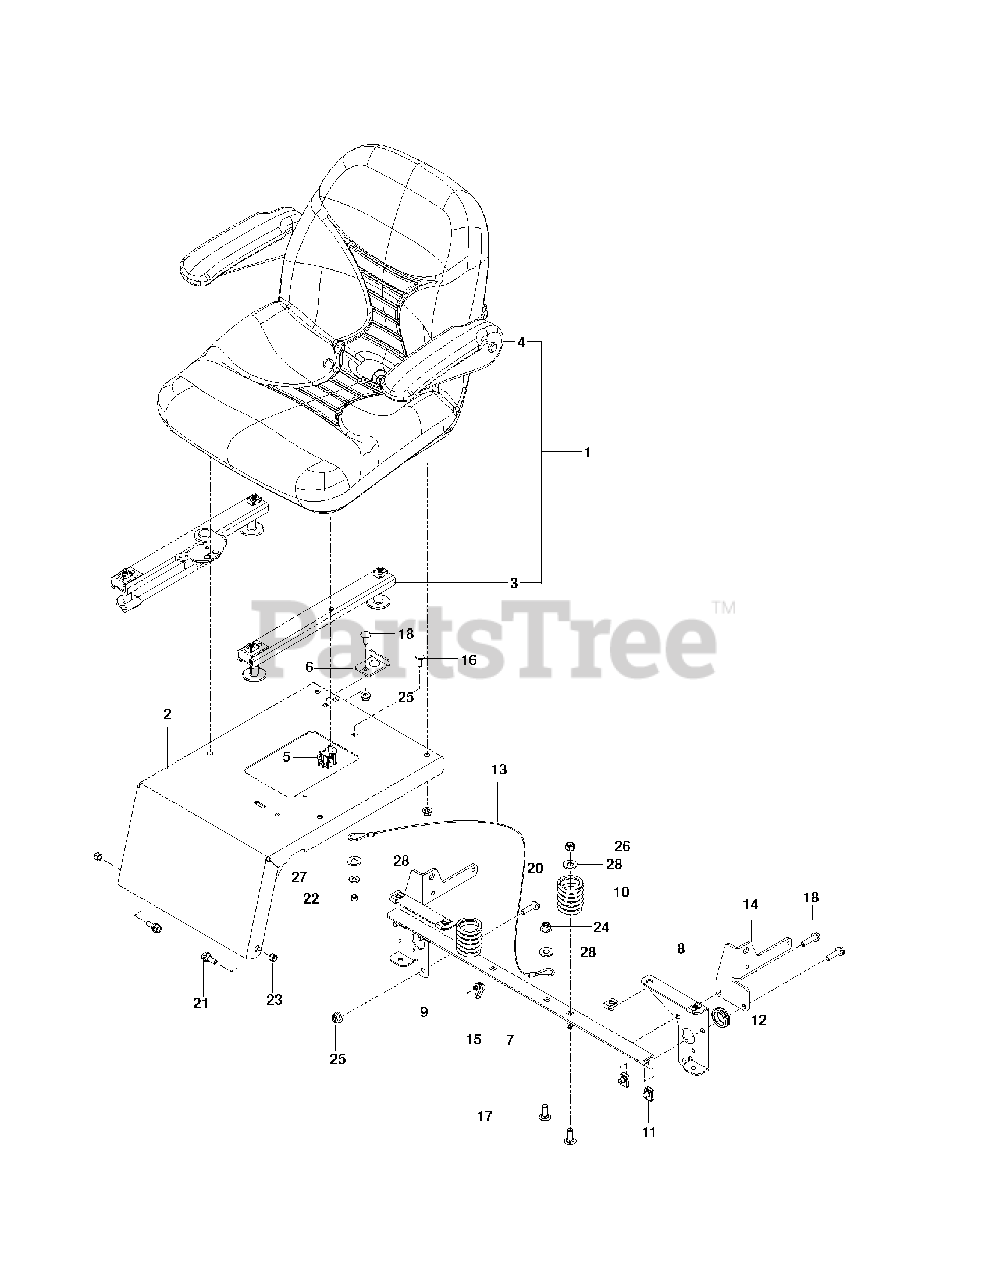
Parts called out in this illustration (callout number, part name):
1	SEAT
2	KIT.SEAT.MOUNT.W/DECAL
3	TRACK ADJUSTMENT KIT
4	ARMREST KIT, LT SQUARE END
5	SWITCH.SNAPMOUNT.NC
6	STOP, SEAT - BLACK
7	SUPPORT, SEAT
8	SUPPORT, LT, BLK
9	SUPPORT, RT, BLK
10	SPRING COMPRESSION
11	U-CLIP 5/16-18 NUT RETAINER
12	RUBBER GROMMET
13	SEAT LANYARD
14	MOUNT, SEAT BELT, BLACK
15	TIE WRAP, 8-3/8", W/CLIP
16	RHSNB 1/4C X 3/4
17	RHSNB 3/8C X 1
18	RHSNB 5/16-18 X 3/4
19	HHFS 5/16-18 X 1.25 TPBLT GD 5
20	HHFS 5/16-18 X 3/4
21	SB 5/16-18 HEX HD GD5, BLK ZN
22	RP_NUT 1/4-20 NYLOC
23	NUT 5/16 NYLOC
24	NUT 3/8-16 HEX FLG NYLOC ZD
25	5/16-18 NYLOC FLANGE NUT
26	NUT 3/8-16 NYLOC
27	WASHER 1/4 FLAT
28	RP WASHER 3/8 FLAT
